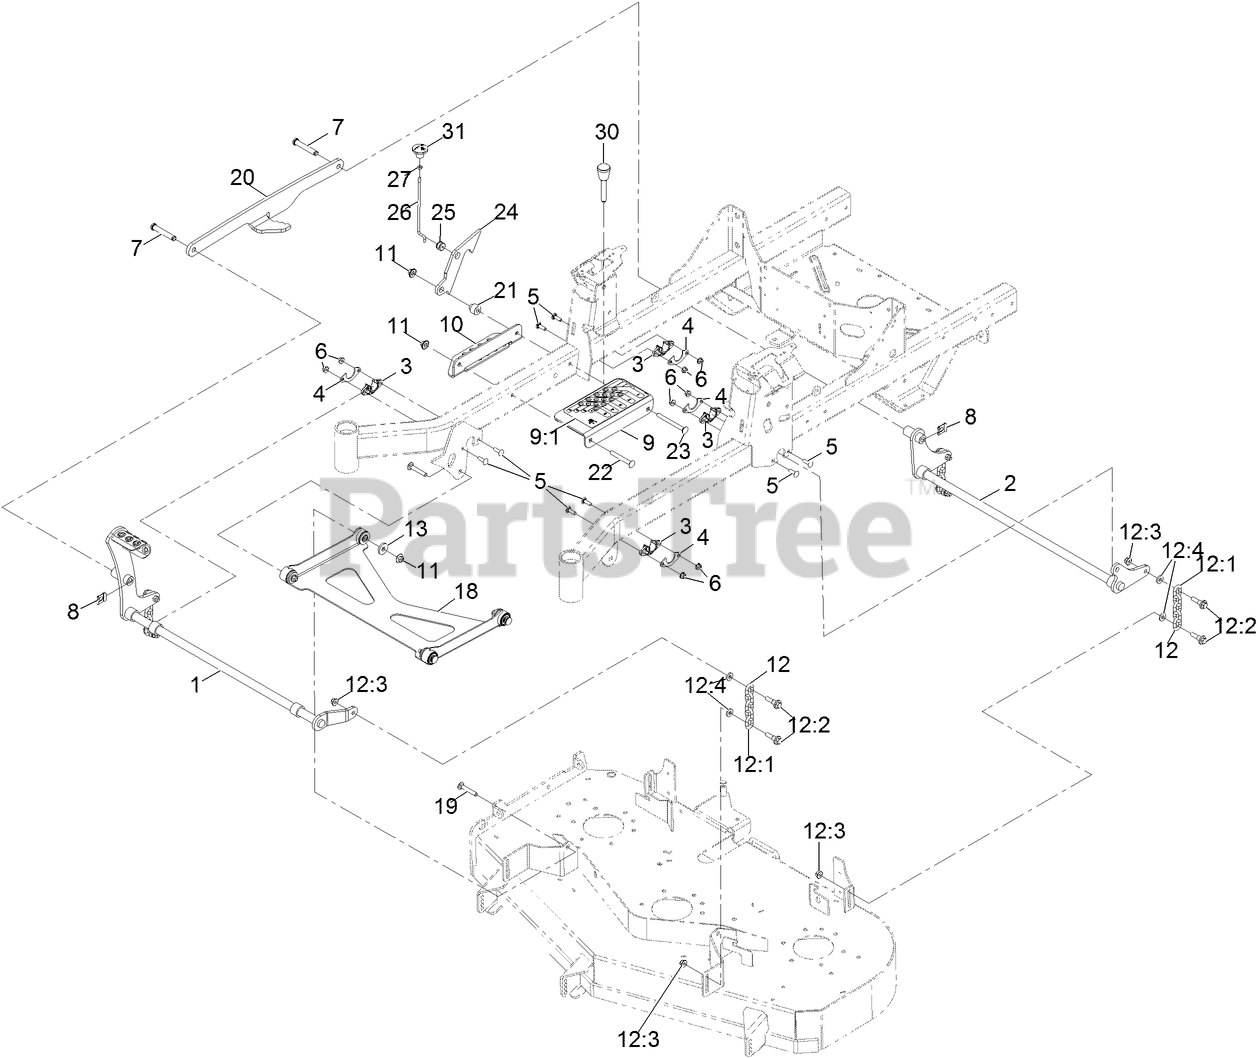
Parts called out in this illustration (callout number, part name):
1	SHAFT-LIFT, DECK
2	SHAFT-LIFT, DECK (REAR)
3	BUSHING-FLANGE
4	GUSSET-LIFT, DECK
5	SCREW-CARR
6	NUT-HF, NI
7	PIN-CLEVIS
8	CLIP-PIN
9	BRACKET ASM
9:1	DECAL-HOC
10	ANGLE-HOC, LOWER
11	NUT-FLANGE, NI
12	DECK CHAIN ASM
12:1	CHAIN-LIFT, DECK
12:2	BOLT-SHOULDER
12:3	NUT-HF, NI
12:4	SPACER
13	WASHER
18	DECK STRUT ASM
19	SCREW-HH
20	LINK-LIFT
21	SPACER-STEPPED
22	SCREW-CARR
23	SCREW-CARR
24	PLATE-LOCK, TRANSPORT
25	GROMMET
26	ROD-LOCK, TRANSPORT
27	NUT-JAM
30	PIN-HOC
